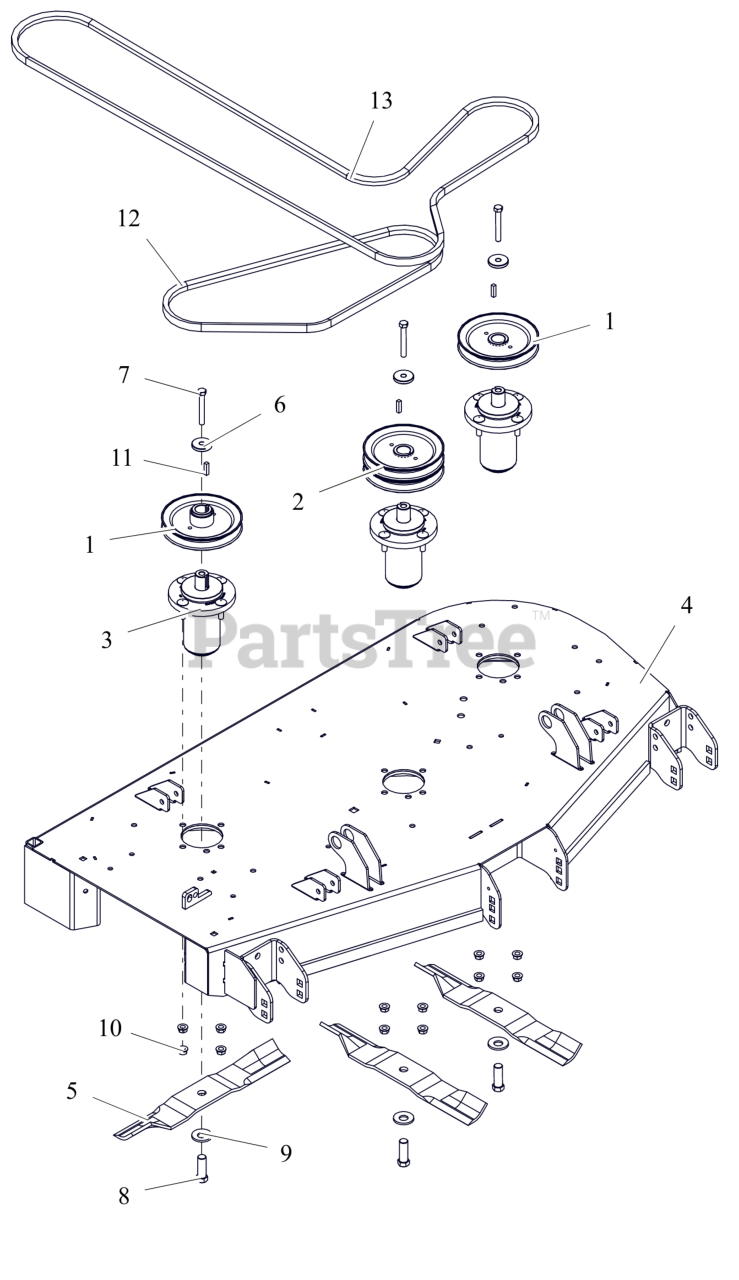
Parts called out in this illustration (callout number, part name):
1	PULLEY, SINGLE-1"ID X 6" OD
2	PULLEY, DOUBLE
3	ASM, MAINT FREE ALUM SPINDLE
4	KIT,DECK-48" W/DECALS - ARIENS
5	BLADE, 16.19" MOWER (HI-LIFT)
6	RETAINER, SHEAVE
7	BLT, HEX .38-16X2.75 G8 ZCC
8	BLT, HEX .62-18X1.75 G8 ZCC
9	WSHR-BLVL .669X1.535X.138
10	NUT-LK-CTR-FLG .375-16 GF ZCC
11	KEY, SQ .25X.25X1.00 RC 40-50
12	V-BELT, B-COGGED
13	V-BELT, HB SECTION
